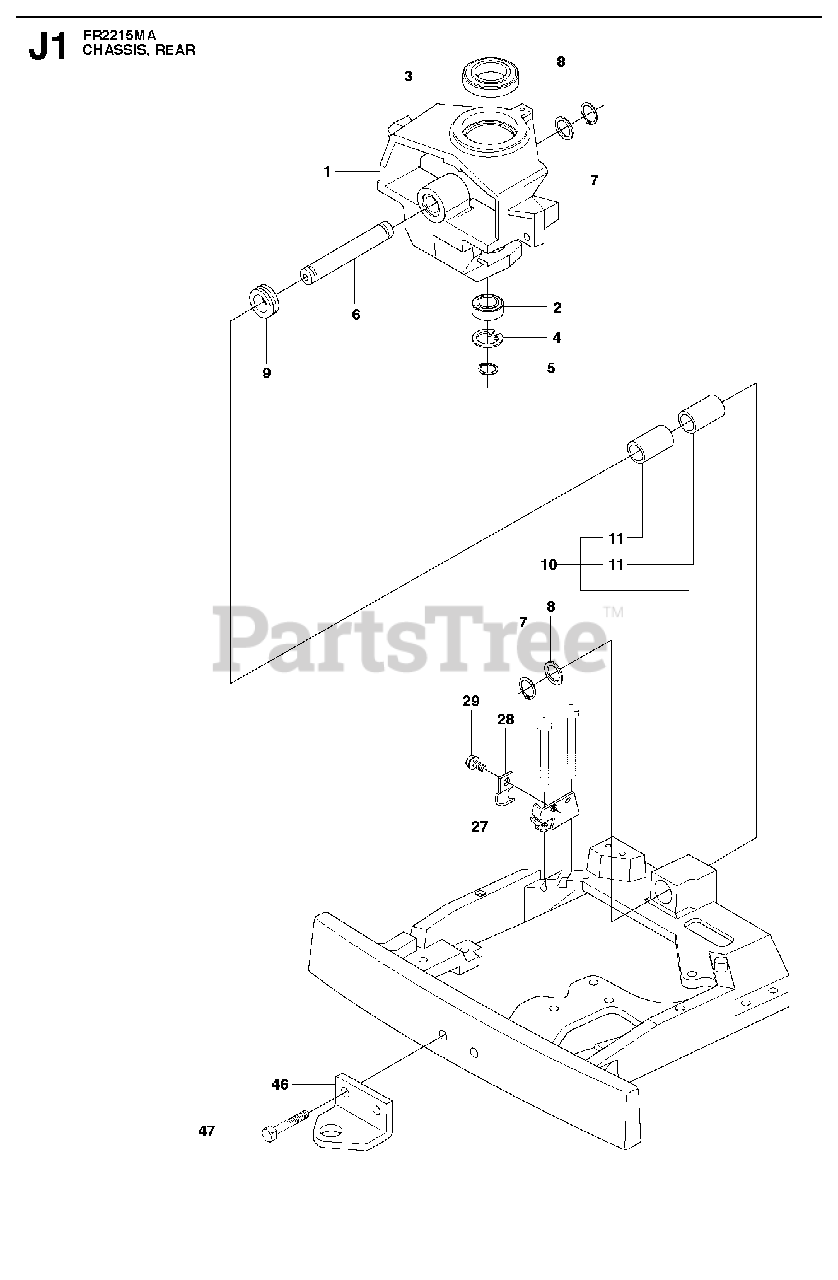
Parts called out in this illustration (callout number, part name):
2	BALL BEARING 6005-2RS
3	BALL BEARING 6010 2RS1
4	CIRCLIP SGH 47
5	RETAINING RING SGA 25
7	RETAINING RING SGA 25
11	BUSHING
46	DRAW RING
47	SCREW M10X25
